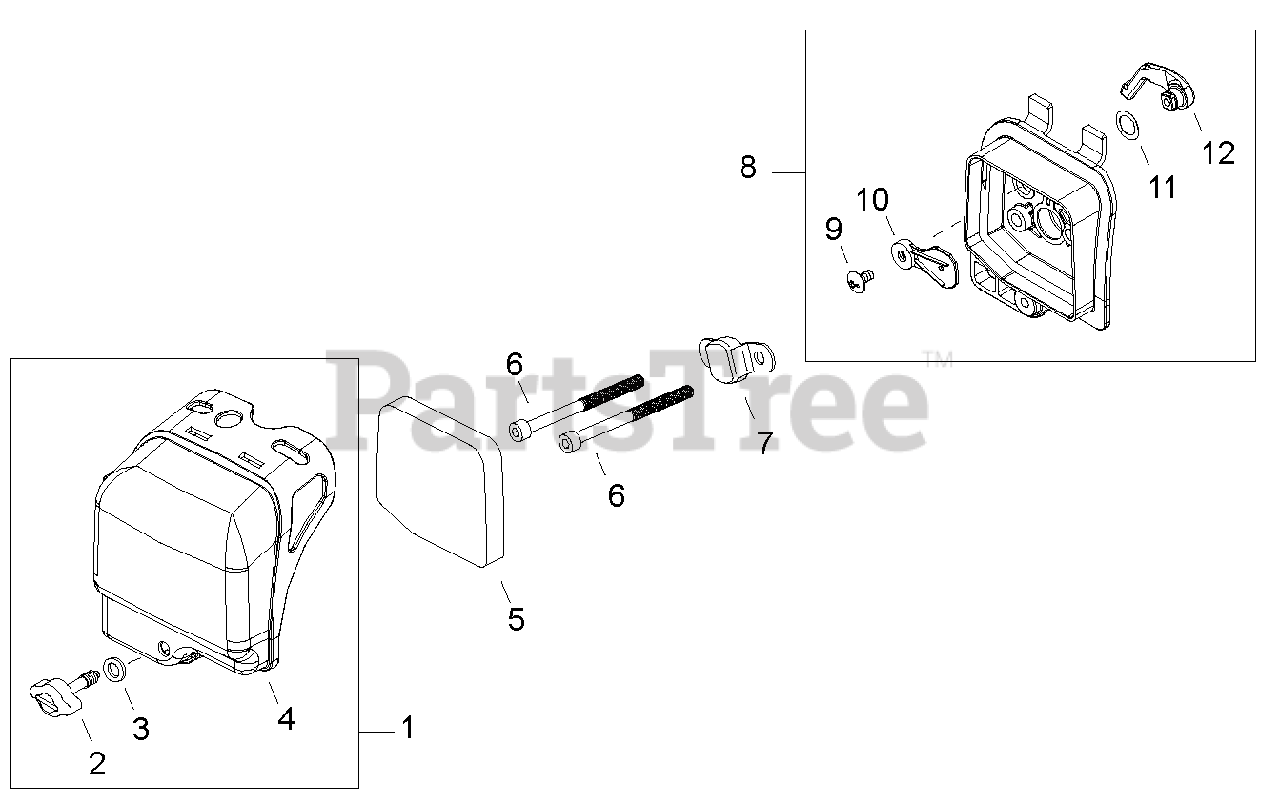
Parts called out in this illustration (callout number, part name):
2	THUMBSCREW
3	WASHER - VYNYL
4	COVER, AIR FILTER
5	FILTER, AIR
6	SCREW - 5X60
7	PLATE, PREVENT
8	AIR FILTER CASE ASSY
8-1	AIR FILTER COVER ASSY
9	SCREW - 4X12
10	PLATE, CHOKE
11	WASHER - WAVE
12	LEVER, CHOKE
